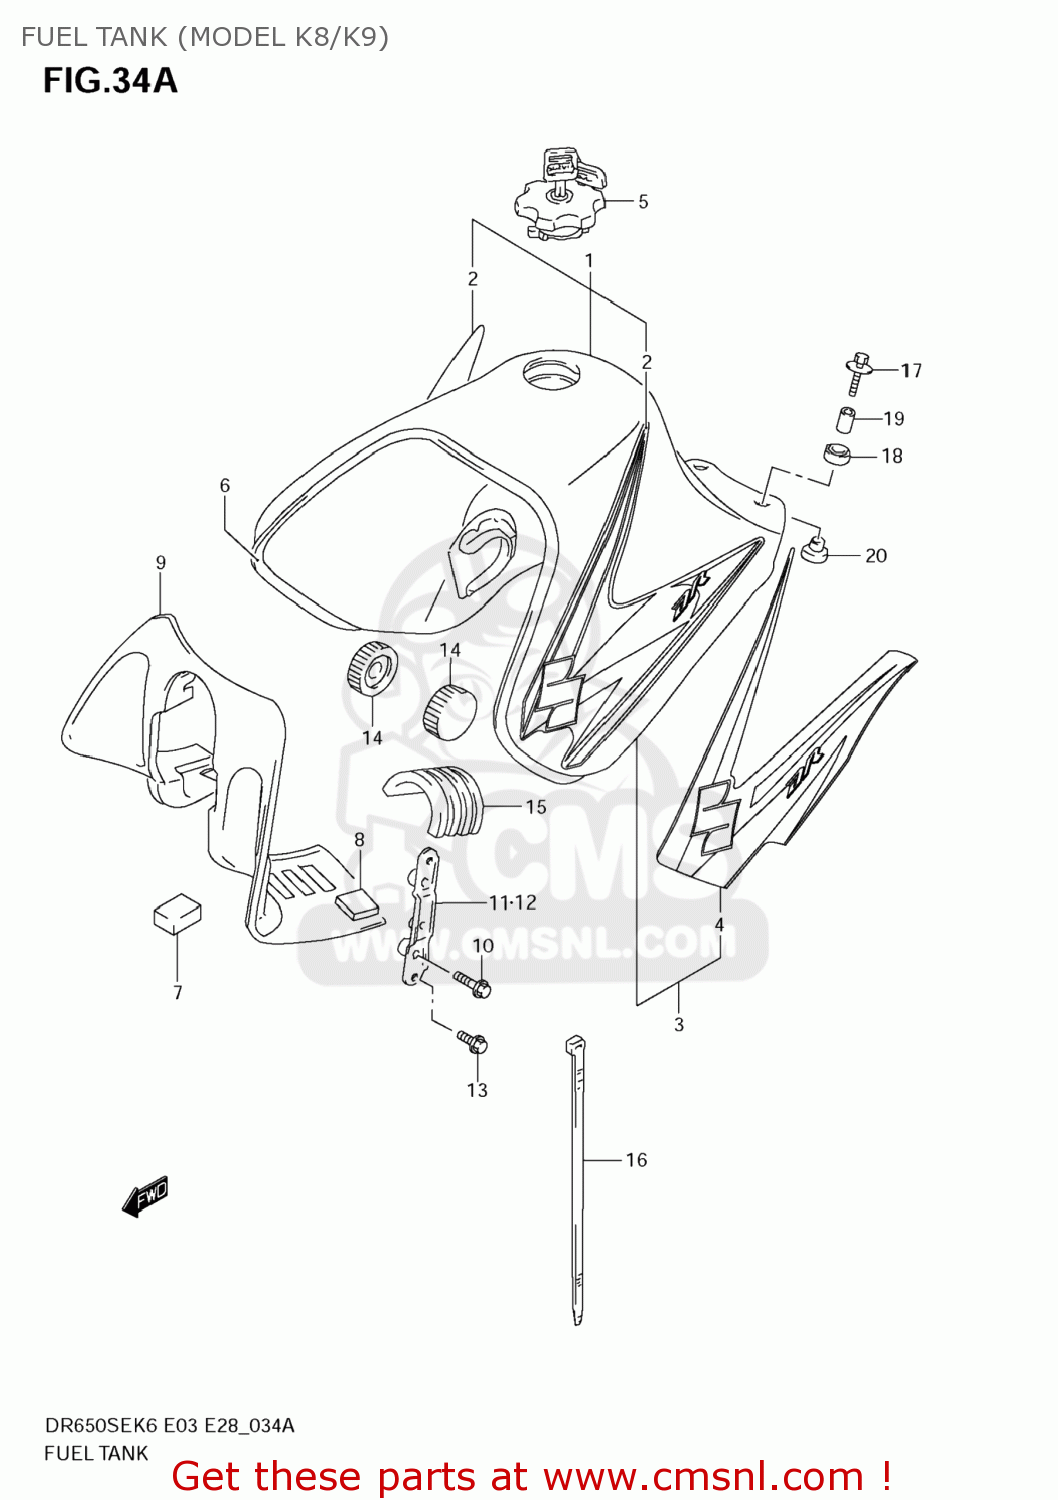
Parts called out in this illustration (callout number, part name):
1	TANK ASSY,FUEL(BLUE)
2	TAPE SET,FUEL TANK
3	TANK ASSY,FUEL(BLACK)
4	TAPE SET,FUEL TANK
5	CAP SET,FUEL TANK
6	MOLDING,FUEL TANK
7	CUSHION,HEAD LAMP HOUSING
8	CUSHION,OIL TANK UPR
9	COVER,FUEL TANK FR
10	BOLT(6X12)
11	BRACKET,FUEL TANK COVER,R
12	BRACKET,FUEL TANK COVER,L
13	BOLT
14	CUSHION,FUEL TANK FR
15	CUSHION,FUEL TANK UPR
16	CLAMP(L:250)
17	BOLT(6X30)
18	CUSHION
19	SPACER(6.5X9X18)
20	CUSHION
